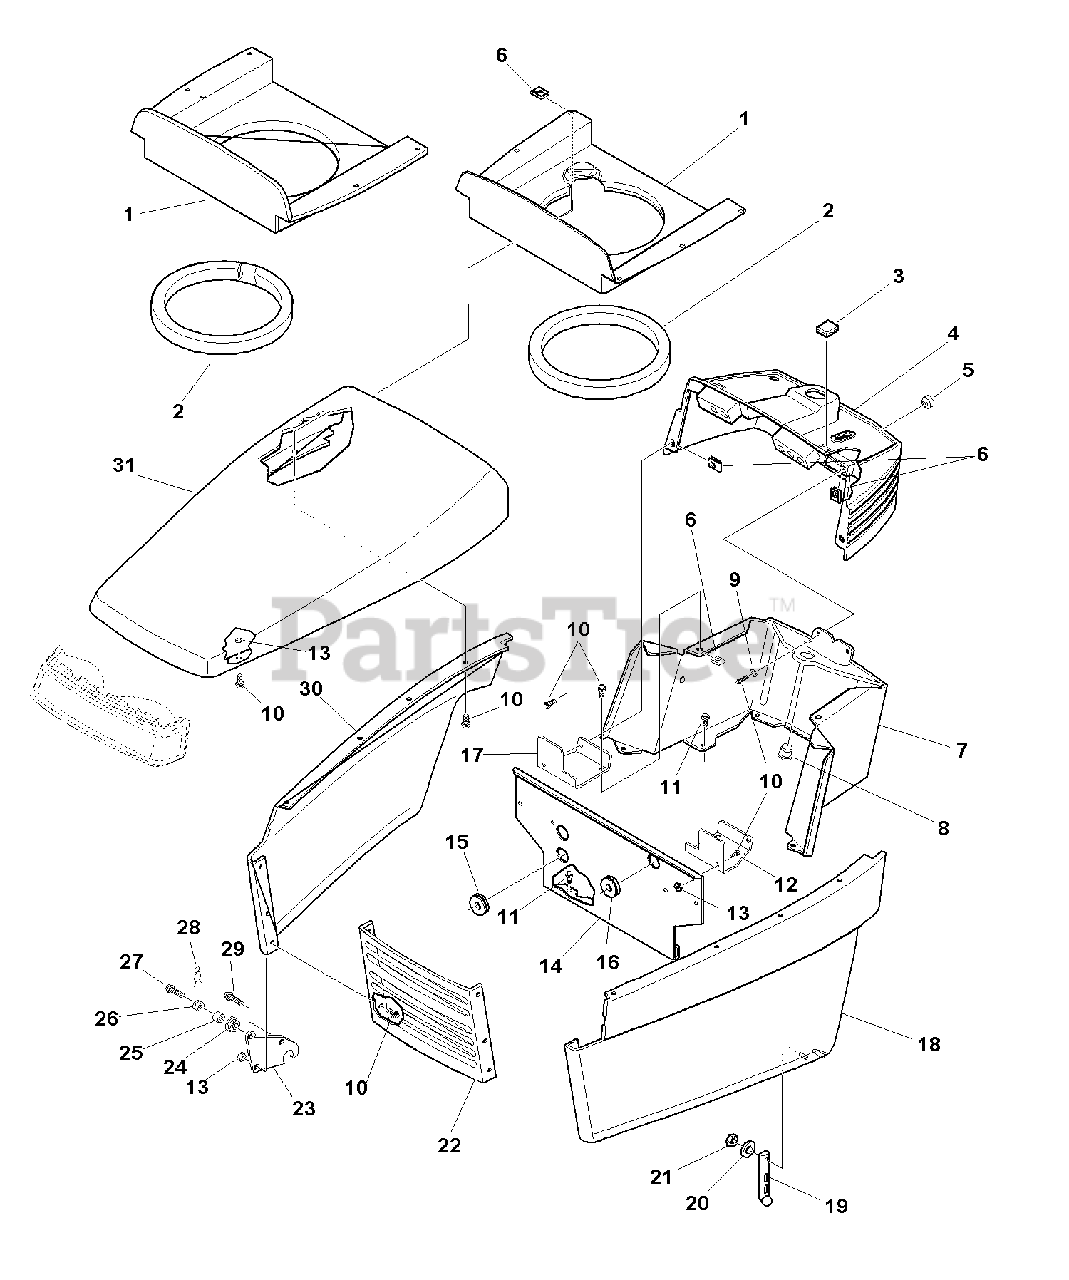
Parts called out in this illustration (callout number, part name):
1	DUCT, Air, 16 HP Kohler
1	DUCT, Air, 17 HP Briggs & Stratton
2	MOULDING, Air Duct, 16 HP Kohler
2	MOULDING, Air Duct, 17 HP Briggs & Stratton
3	PLUG, Dash Hole
4	DASH ASSRMBLY
5	PLUG, Bumper
6	SPEEDNUT, 1/4-20
7	DASH, Lower
9	WASHER
10	SCREW, Hex Flange Whizlock, 1/4-20 x 5/8
11	SCREW, Hex Washer Head Taptite, 1/4-20 x 1/2
12	SUPPORT, Bulkhead, LH
13	NUT, Hex Nylon Lock, 1/4-20
14	BULKHEAD
15	GROMMET, Wire Harness
16	GROMMET, Bulkhead
17	SUPPORT, Bulkhead, RH
18	SIDE PANEL ASSEMBLY, LH, Orange
18	SIDE PANEL ASSEMBLY, LH, Red
19	STRAP, Hood
20	WASHER, Special
21	NUT, Hex Nylon Lock, #10-24
22	GRILLE
23	HINGE, Hood
25	PIVOT, Hood
26	SPACER, Hood
27	SCREW, Hex Washer Head, Taptite, 5/16-18 x 1
28	CLIP, Hairpin
29	SCREW, Hex Washer Head, Taptite, 5/16-18 x 5/8
30	SIDE PANEL ASSEMBLY, RH, Orange
30	SIDE PANEL ASSEMBLY, RH, Red
31	HOOD, Orange
31	HOOD, Red
